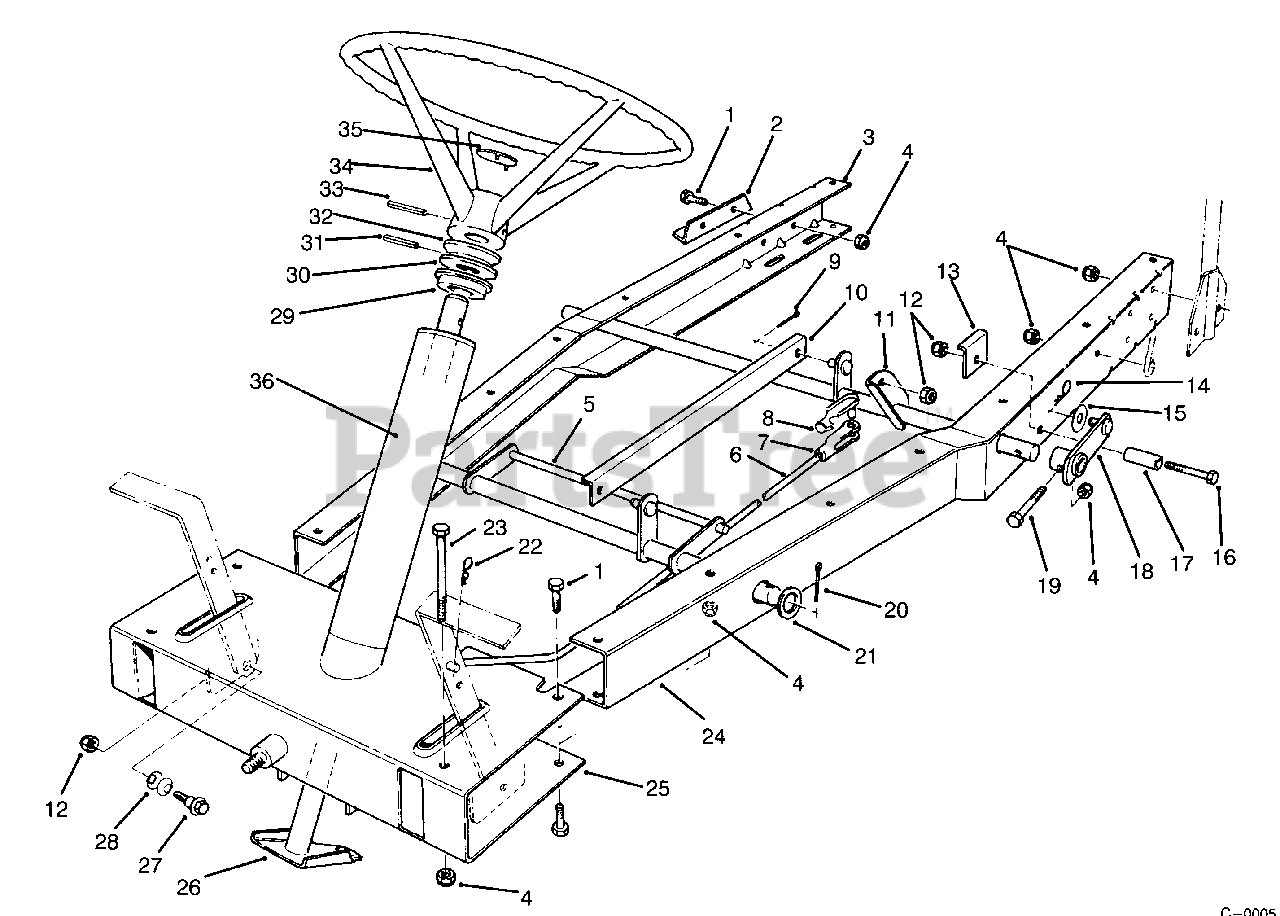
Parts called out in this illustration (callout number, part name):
1	Screw-Cap Hex. Hd.
2	Mount-Bearing, Axle
3	Channel-R.H.
4	Nut-Lock
5	Lift W.A.-Front, Deck
6	Rod-Clutch
8	Assembly-Pin, Clevis
9	Pin-Cotter
10	Bracket-Link, H.O.C.
11	Tube W.A.-Support, Rear
12	Nut-Lock
13	Brace-Stop, Deck
14	Pin-Hair, Cotter
15	Washer-Flat
16	Screw-Cap Hex. Hd.
17	Spacer-Stop, Deck
18	Lever W.A.-H.O.C.
19	Bolt-Mounting, Axle
20	Pin-Cotter
21	Washer-Flat
22	Pin-Hair, Cotter
23	Screw-Cap Hex. Hd.
24	Channel-L.H.
25	Frame W.A.-Front
26	Shaft W.A.-Steering
27	Bolt-Shoulder
28	Washer-Belleville
29	Bushing-Steering
30	Washer-Steering
32	Spacer-Steering
34	Wheel-Steering
35	Insert-Wheel, Steering
